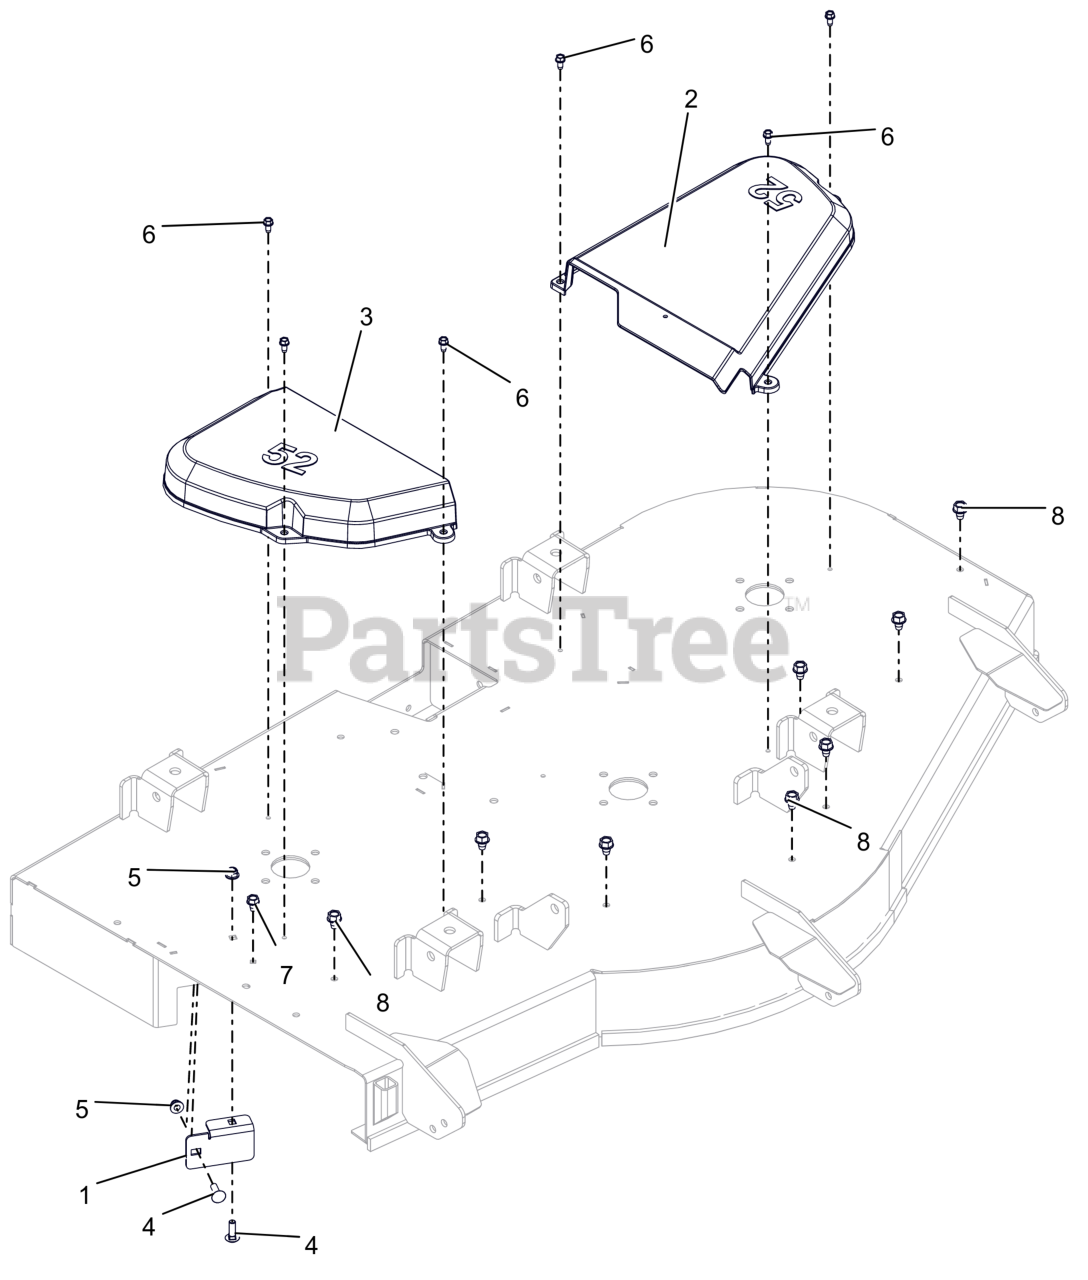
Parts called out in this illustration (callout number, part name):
1	STRIP, DEFLECTOR - 52"
2	COVER, BELT 52" LH
3	COVER, BELT 52" RIGHT
4	BLT,RHSN .31-18X1.00 G5 ZCC
5	NUT,LK-NYL-FLG .31-18 G5ZC120
6	SCR-TAP .25-20X.50 HWH ZCC
7	SCR,TAP .312-18X.50 HWH TR ZCC
8	SCR,TAP .375-16X.50 HWH TR ZCC
